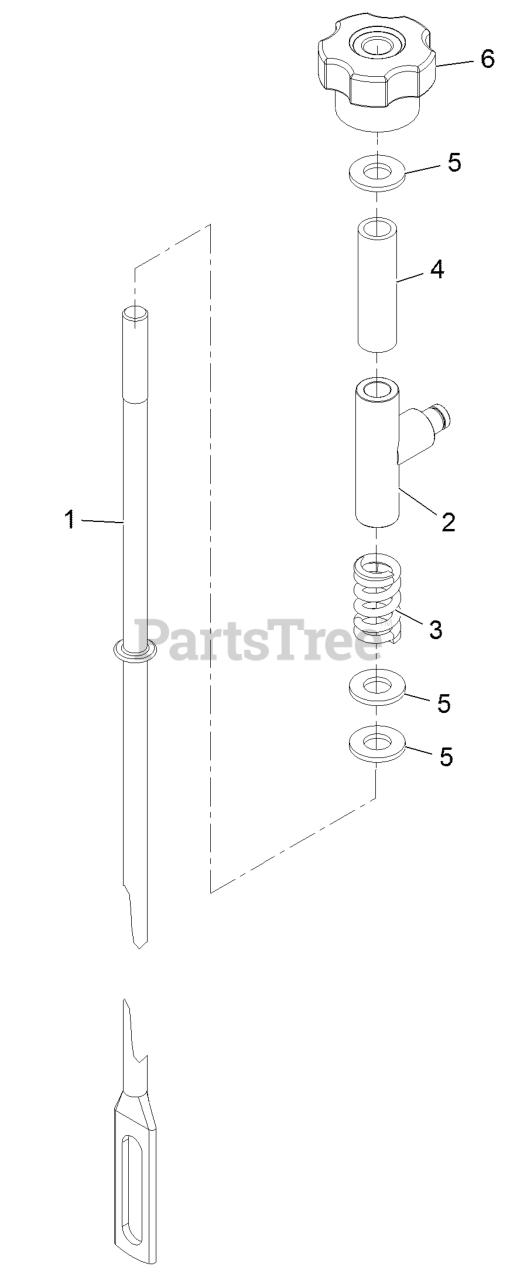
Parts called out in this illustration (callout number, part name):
1	ROD, RIGHT
3	SPRING, COMPRESSION
5	WASHER-FLAT
